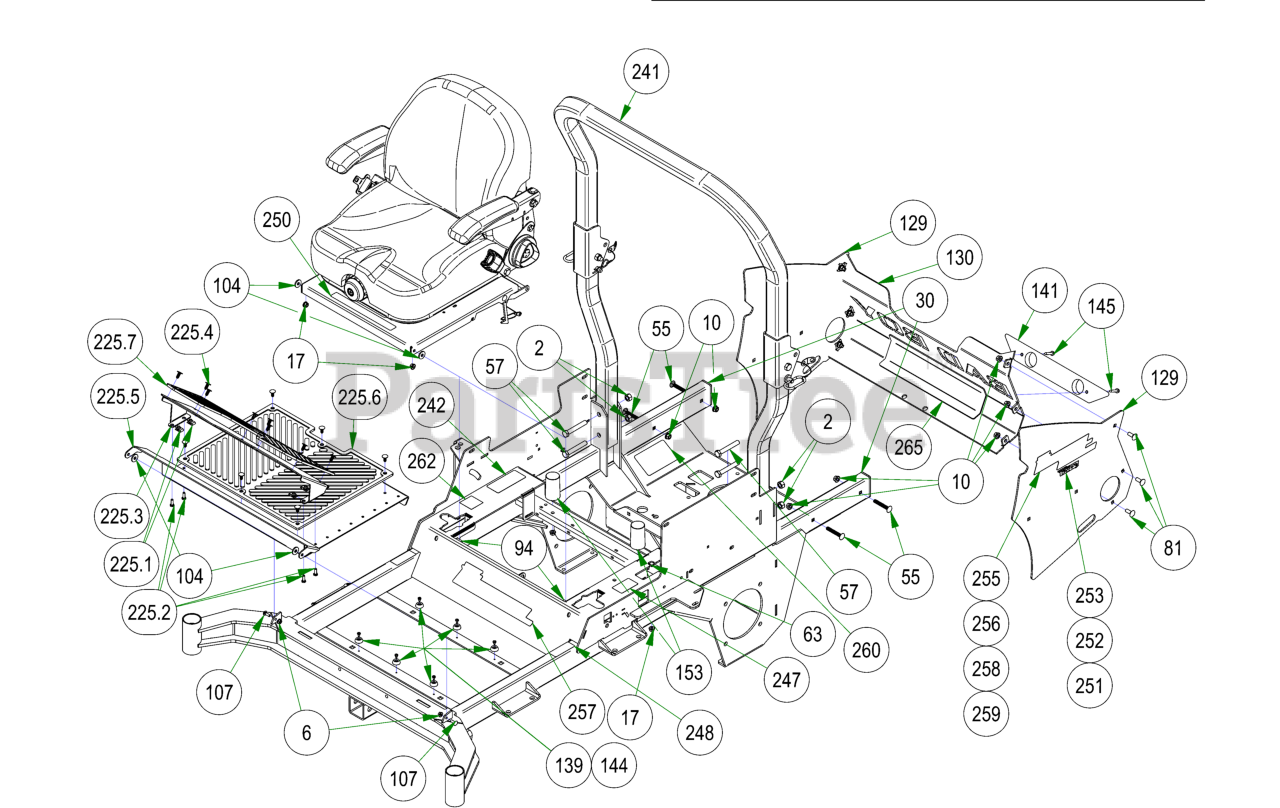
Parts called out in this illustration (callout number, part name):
2	1/2-13 HEX 2-WAY REVERSIBLE CENTER LOCKNUT Grade B ZINC
6	1/4-20 NYL INSERT FLANGE LOCKNUT ZINC
10	3/8-16 NYLON INSERT FLANGE LOCKNUT (GR.F) ZINC
17	5/16-18 NYLON INSERT FLANGE LOCKNUT ZINC
20	5/16-18 HEX SERRATED FLANGE NUT HARD/ZINC
30	1 1/2 x 3 Frame Plug
51	M6-1.0 X 16MM DIN 933 HEX TAP BOLT (CL 8.8) ZINC
55	3/8" x 2 1/2" Carriage Bolt
57	1/2-13 X 3-1/4 HEX CAP SCREW (GR.5) ZINC
63	5/16-18 X 1 HEX CAP SCREW (GR.5) ZINC
81	3/8-16 X 1 CARRIAGE BOLT (GR.5) ZINC
94	5/16-18 X 1 CARRIAGE BOLT (GR.8) ZINC
104	.360 ID X .983 OD X .120 THICK FLAT WASHER NYLON
107	1/4-20 X 3/4 CARRIAGE BOLT (GR.5) ZINC
128	R-SERIES SEAT PLATE ASSEMBLY
129	Rebel Rear Cover Side Plate
130	2019 Vertical Rear Cover Tailgate - Black
139	Button Bumper
141	2017 XP Bumper
144	10-16 X 1/2 PAN PHIL TEK/3 CLIMASEAL OR ACF-SILVER COATED
145	1/4-14 X 1-1/2 HEX WASHER UNSLOT TEK/3 ZINC
153	2019 Bad Boy X Cylindrical Seat Mount
209	2019 Outlaw EPA Cannister Assembly
218	2022 Rebel Frame
219	2021 Rebel Seat
225	R-Series Floorboard Assembly
225.1	1/4-20 Cage Nut
225.2	1/4-20 X 3/4 HEX CAP SCREW (GR.5) ZINC
225.3	OUTLAW ADJUSTABLE FOOT PLATE-ORANGE
225.4	Ratchet Fastener
225.5	2019 Outlaw Floorboard
225.6	MAT (FLOOR)
225.7	MAT (FOOT PLATE)
241	2019 2X2 Folding ROPS
242	EPA Build Date Punch Label
247	2018 Out/XP/Diesel Brake Decal
248	2018 LH/RH Steering Control Decal Roll
250	Outlaw Warning Decal
251	2022 Powered By Vanguard Decal
252	2022 Powered By Kawasaki Decal
253	2022 Powered By Kohler Decal
255	2019 Rebel 852cc Backplate Cluster
256	2019 Rebel 993cc Backplate Cluster
257	2019 Rebel Cooler Cover Decal
258	2019 Rebel 747cc Backplate Cluster
259	2019 Rebel 999cc Backplate Cluster
260	2019 Rebel Pump Belt Route Decal
262	2019 Deck Release Decal
263	Control Adj. Control Rod Decal
264	Control Adj. Control Dampener Decal
265	Heat Shield (Fiberglass Adhesive)
